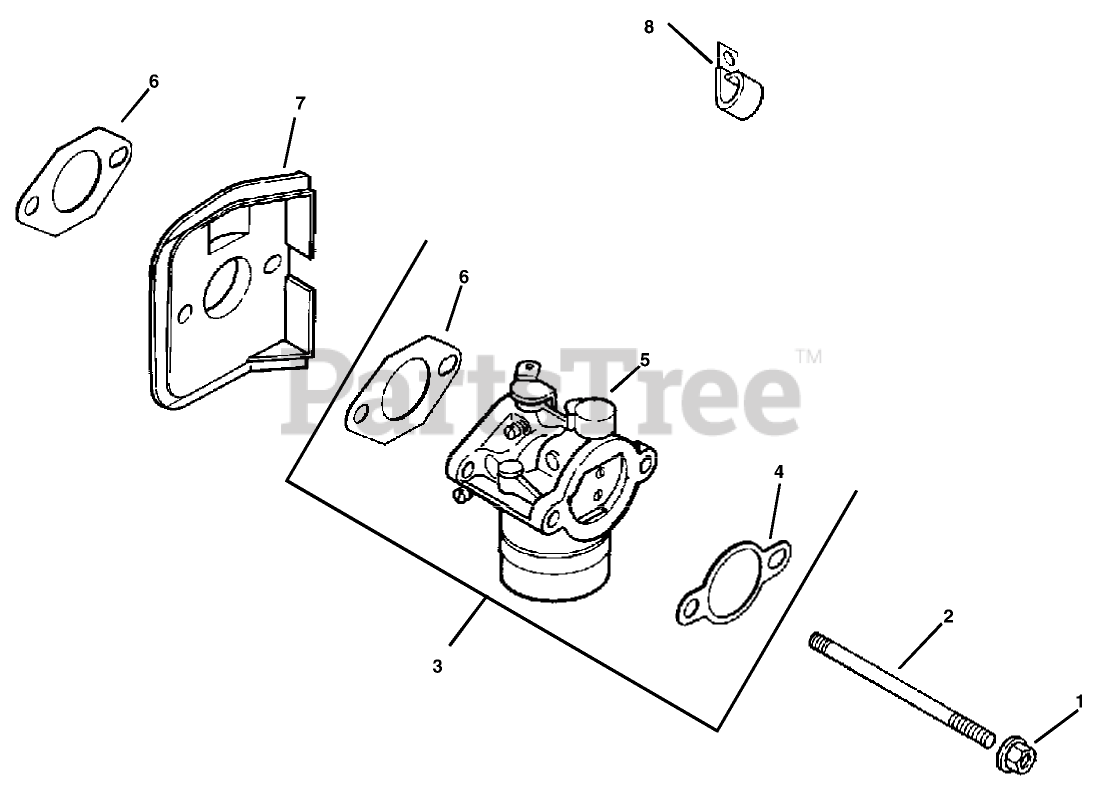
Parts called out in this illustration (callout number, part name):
1	NUT-FLANGE (M6X1.0)
2	Stud (M6x1.0x116)
3	Kit-Carburetor w/Gaskets (Incl. 4-6)
4	Gasket-Base, Air Cleaner
5	Carburetor ASM
6	Gasket-Carburetor
7	Deflector-Heat
8	CLIP-CABLE
